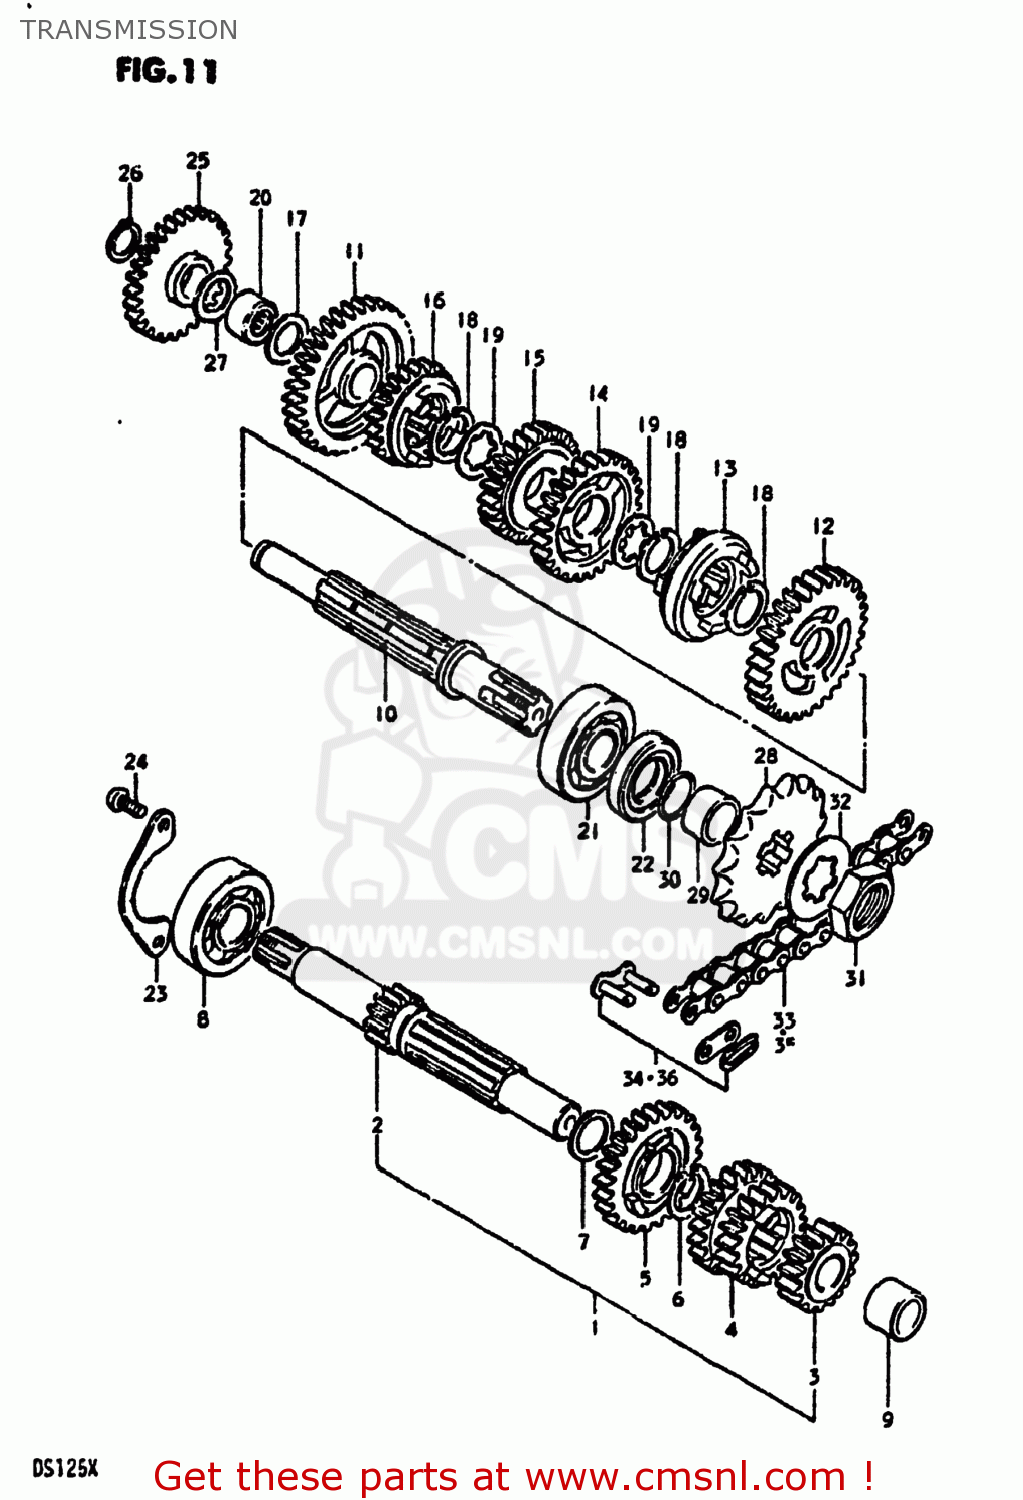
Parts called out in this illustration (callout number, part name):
1	SHAFT ASSEMBLY,COUNTER
2	SHAFT,COUNTER
3	GEAR,SECOND DRIVE
4	GEAR,THIRD/FOURTH DRIVE
5	GEAR,FIFTH DRIVE
6	CIRCLIP
7	WASHER
8	Bearing
9	BUSH(15X22X15)
10	SHAFT,GEAR SHIFT
11	GEAR,1ST DRIVEN
12	GEAR,SECOND DRIVEN
13	WHEEL,SECOND DRIVEN GEAR
14	GEAR,THIRD DRIVEN
15	GEAR,FOURTH DRIVEN
16	GEAR,FIFTH DRIVEN
17	WASHER,THRUST
18	CIRCLIP
19	WASHER,LOCK
20	BEARING(15X22X12)
21	Bearing
22	SEAL,OIL(25X40X7)
23	RETAINER,CNTR SHAFT BEARING
24	SCREW 6X12
25	GEAR,KICK STARTER IDLE
26	CIRCLIP,15MM
27	WASHER,THRUST
28	SPROCKET,ENGINE
29	SPACER(20X25X12.5)
30	O RING(D:1,ID:19.5)
31	NUT
32	WASHER,LOCK
33	CHAIN ASSEMBLY,DRIVE
34	JOINT ASSEMBLY,CHAIN
35	CHAIN ASSEMBLY,DRIVE
36	JOINT ASSEMBLY,CHAIN
